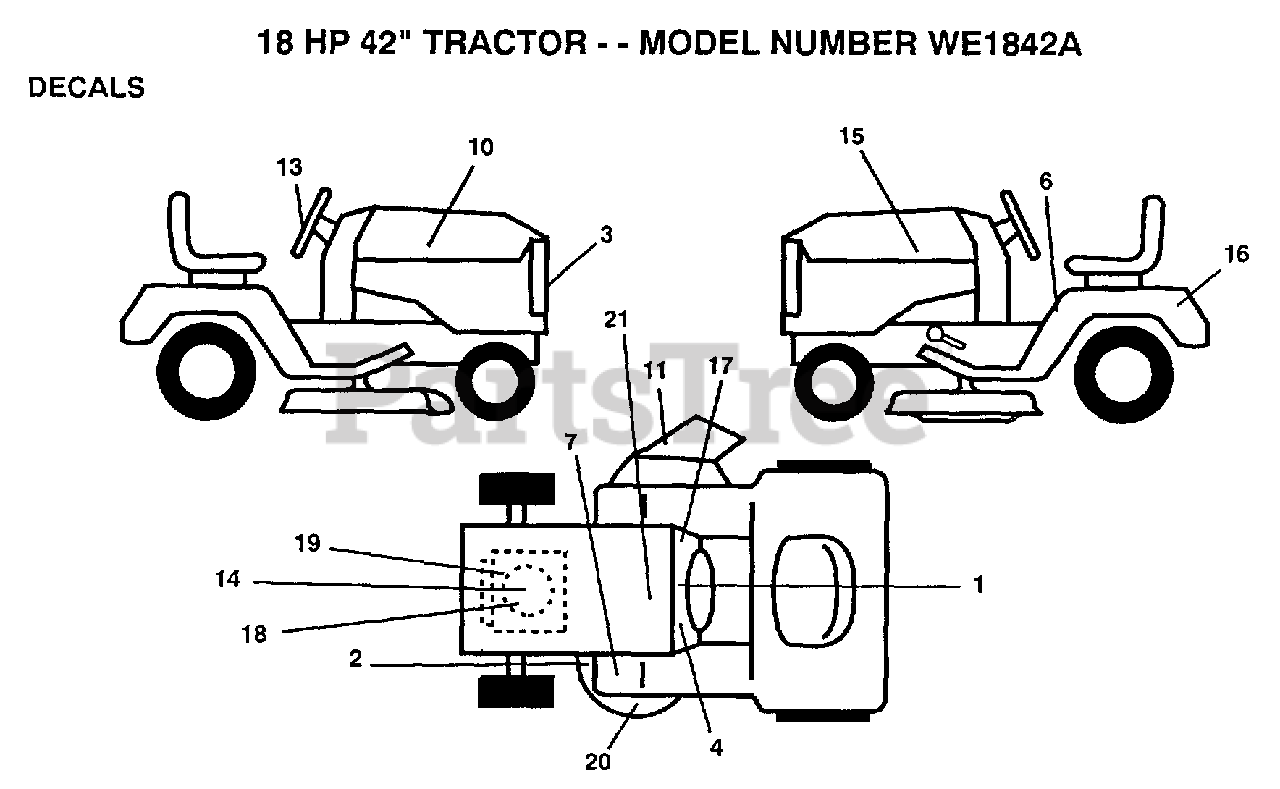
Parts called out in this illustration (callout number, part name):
1	DECAL.DASH.INSTR.
2	DECAL
3	DECAL.GRILL
6	DECAL CAUTION
7	DECAL T
10	DECAL.HOOD.RH
11	"DECAL, WARNING"
13	DECAL.WHL.STRG.
14	DECAL.ENG.272757
15	DECAL.HOOD.LH
16	DECAL.FENDER
18	DECAL.ENG.272101
20	DECAL.MOWER
21	DECAL
